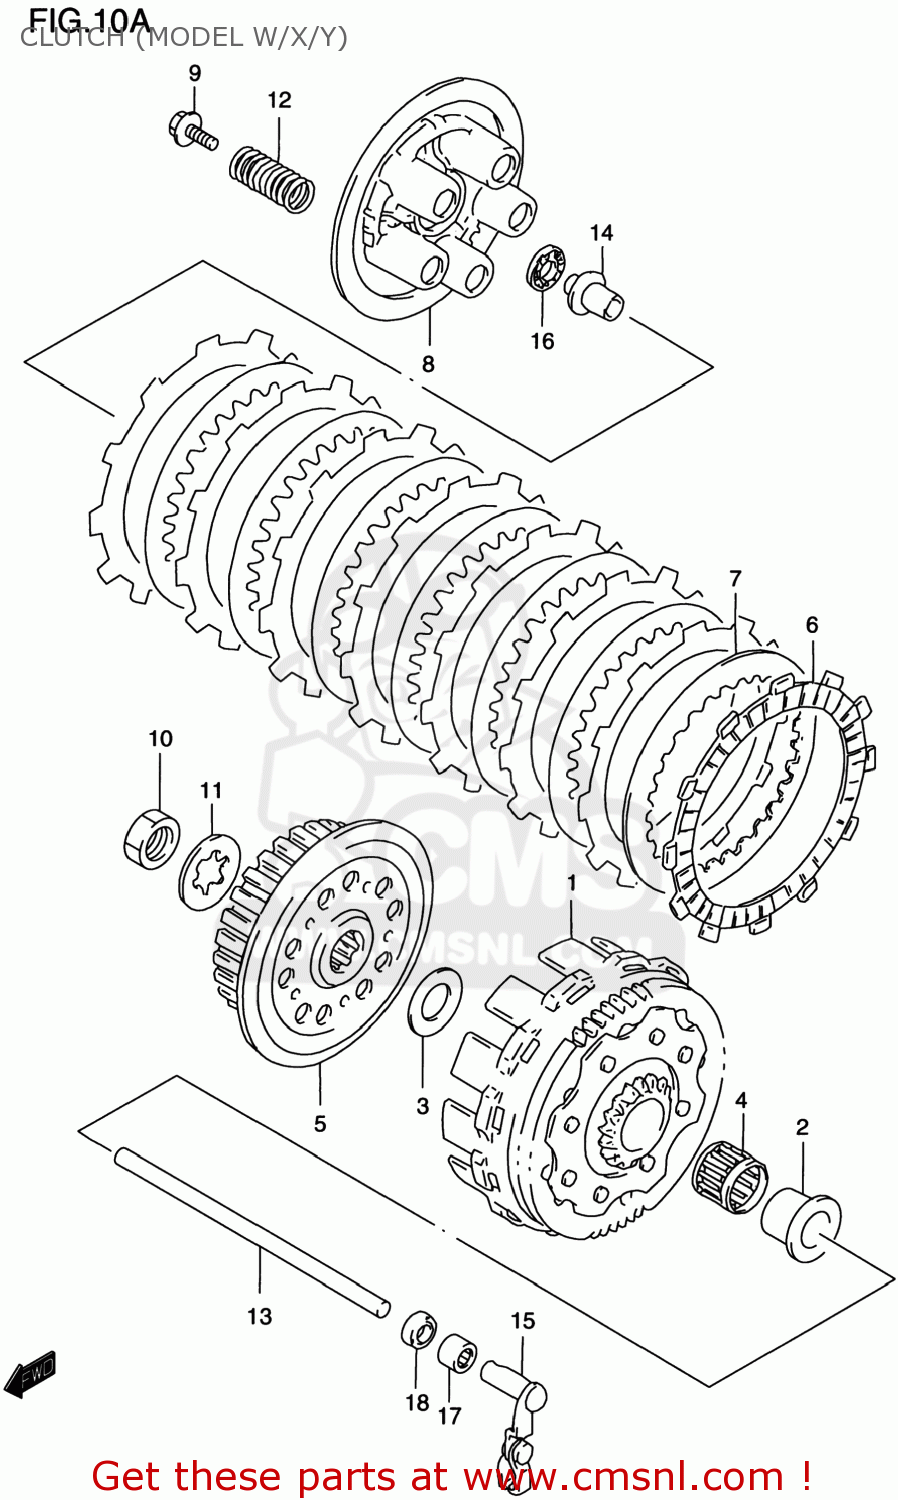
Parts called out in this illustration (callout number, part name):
1	GEAR ASSY,PRI DRIVEN
2	SPACER,PRIMARY DRIVEN GEAR
3	WASHER
4	BEARING(25X30X22)
5	HUB,CLUTCH SLEEVE
6	PLATE,CLUTCH DRIVE T:2
7	PLATE,CLUTCH DRIVEN T:
8	DISC,CLUTCH PRESSURE
9	BOLT(5X25)
10	NUT
11	WASHER,LOCK
12	SPRING
13	ROD,CLUTCH PUSH
14	PIECE,CLUTCH PUSH
15	CAMSHAFT,CLUTCH RELEASE
16	BEARING(10X22X2.8)
17	BEARING(10X14X15)
18	SEAL,OIL(10X17X5)
